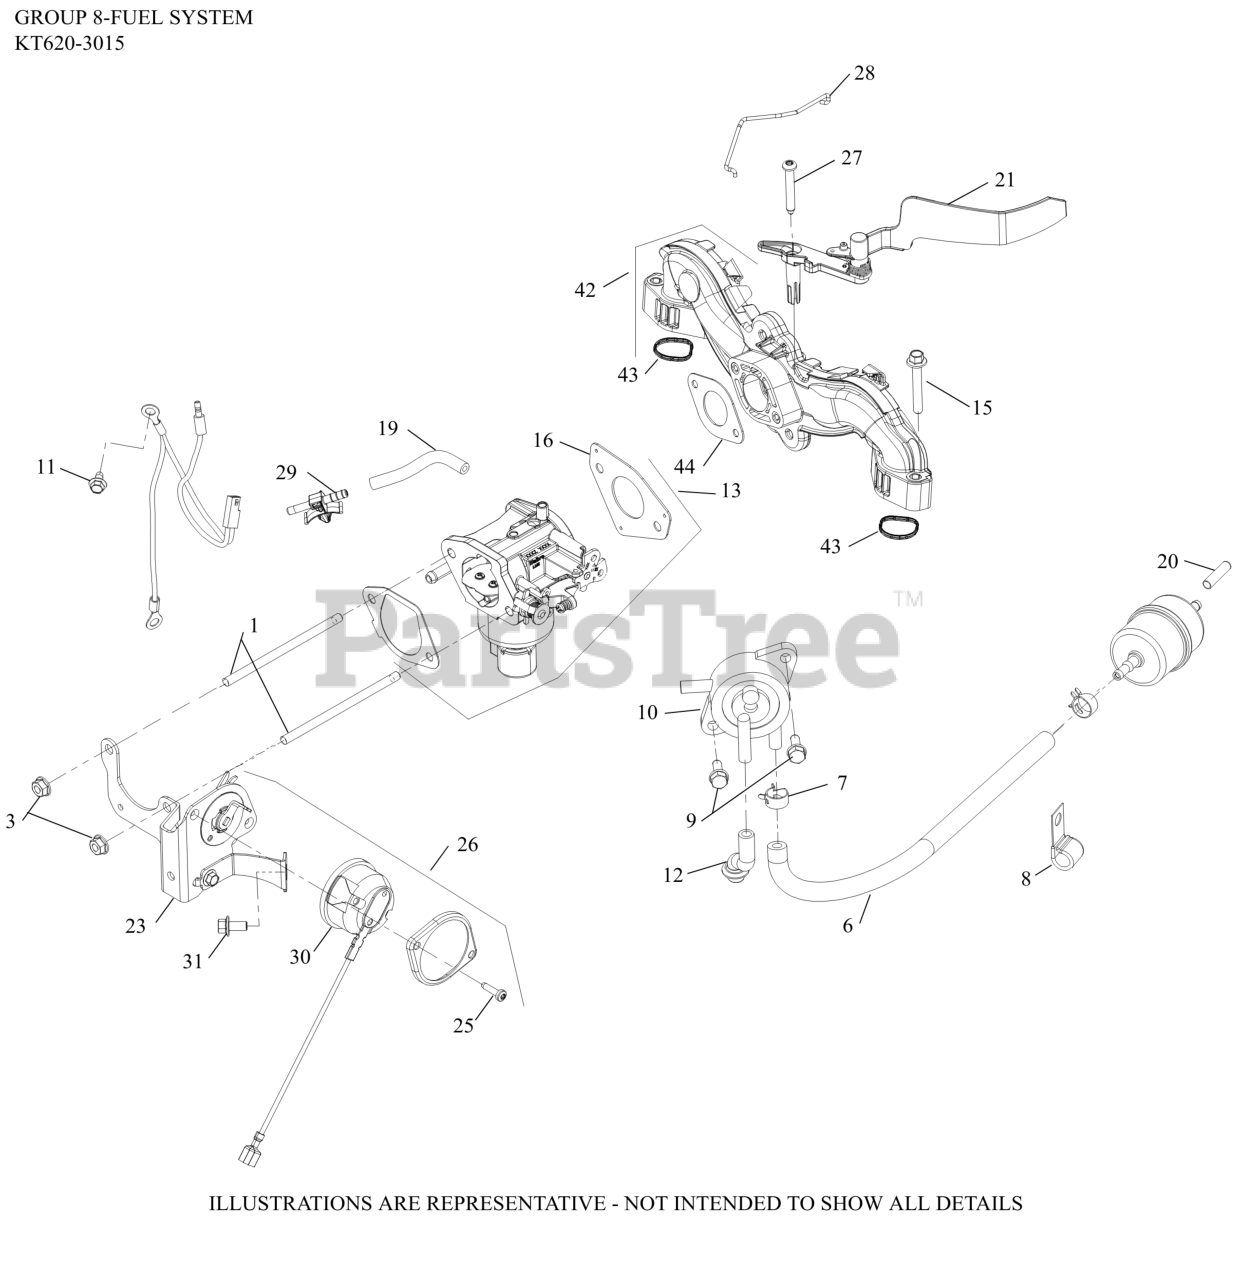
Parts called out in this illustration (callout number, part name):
3	NUT, FLG M6X1.0
6	HOSE,LW PERM.FUEL 24.00"-USE 25 111 81-S
7	SPRING CLAMP, HOSE
8	CLIP, CABLE (KM)
9	SCREW, TAP M6X1.7X18
10	PUMP, FUEL (PULSE)-(#2539326S)
11	SCREW, THREAD FORMING
12	HOSE, PULSE PUMP(STEEL COVERS)
13	KIT,CARB(WALBRO)
15	SCREW, FLG M6X1.0X40
16	GASKET, CARBURETOR
19	HOSE EVAPORATIVE (WALBRO)
20	CAP, MASKING
21	DEFLECTOR ASSEMBLY, AIR VANE
23	BRACKET ASSY, AUTO-CHOKE (MECH)
25	SCREW, PAN HEAD THREAD FORMING (M4)
26	THERMOSTAT ASSY (CDI) - USE 32 755 27-S
27	SCREW, PAN HEAD (#12-14 X 38 MM)
28	LINKAGE, CHOKE UPLOADER
29	CONNECTOR, EVAPORATIVE
30	KIT, THERMOSTAT, ELECTRIC CHOKE
31	SCREW, FLG M6X1.0X12
42	INTAKE MANIFOLD W/GASKETS
43	O-RING, INTAKE PORT
44	GASKET, CARBURETOR (PIM, CV)
NI	KIT,REPAIR OVERHAUL(WALBRO)
NI	KIT,BOWL O-RING(WALBRO)
NI	KIT, HI ALTITUDE (5000 FT) 19MM
NI	KIT,SOLENOID REPAIR(WALBRO)
NI	KIT,REPAIR FLOAT(WALBRO)
